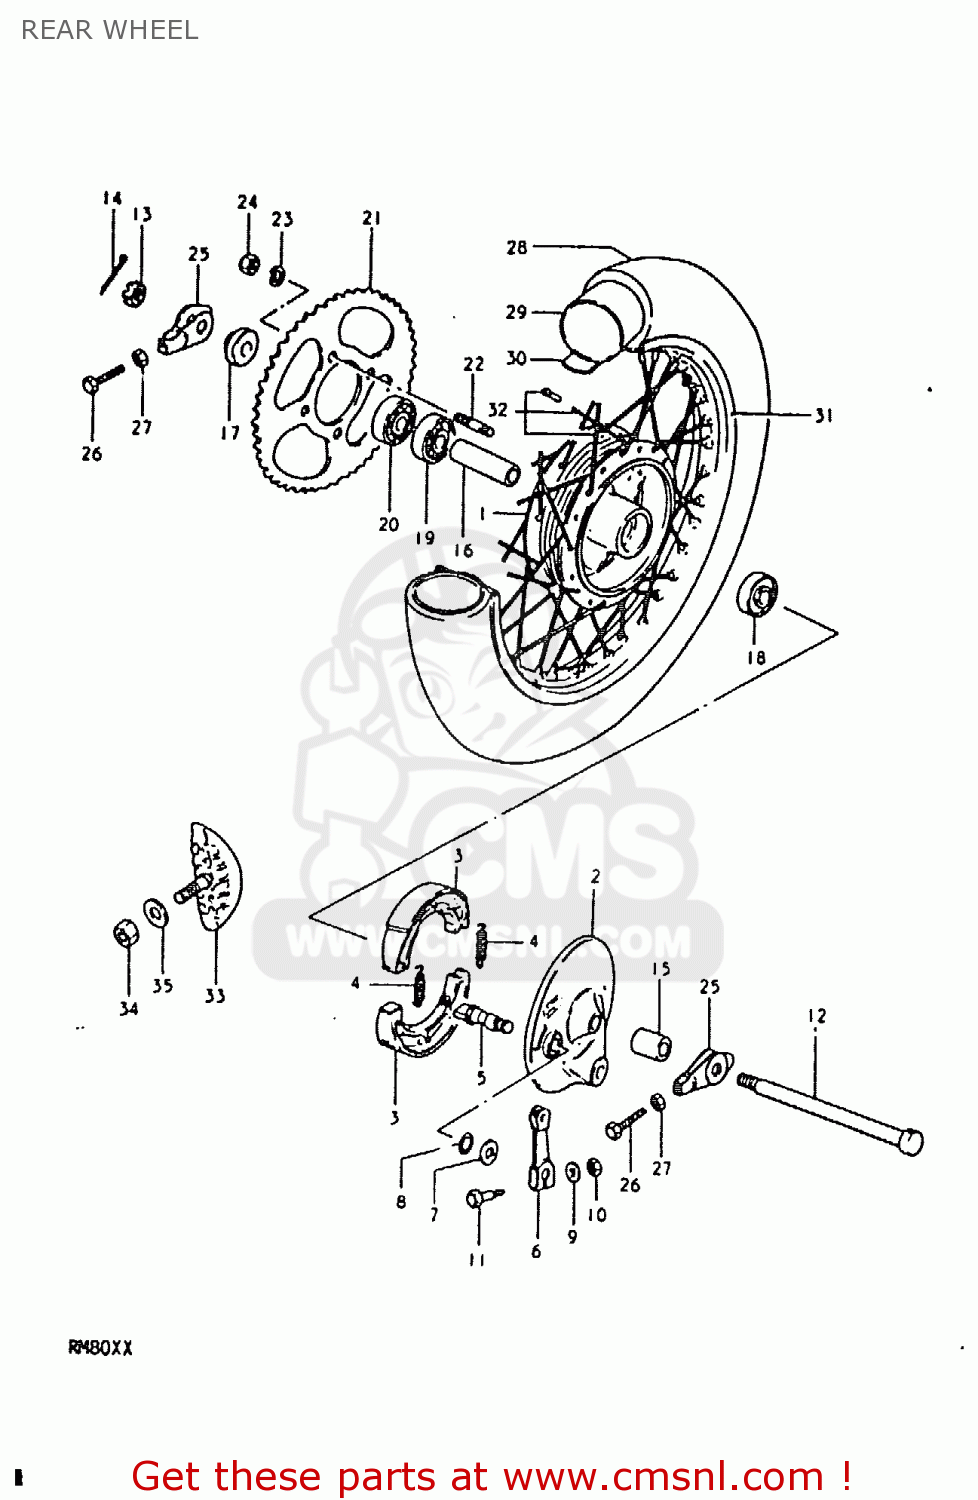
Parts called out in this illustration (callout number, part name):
1	DRUM SET,REAR HUB
2	PANEL,REAR BRAKE ANCHOR
3	SHOE,BRAKE (MCA)
4	SPRING(L:34)
5	CAM,FRONT BRAKE
6	LEVER,RR BRAKE CAM
7	WASHER (14.5X22X1.6)
8	O-RING (D:2.4 ID:13.8)
9	WASHER
10	NUT
11	BOLT(6X33)
12	AXLE,REAR
13	NUT 12MM
14	COTTER PIN
15	SPACER (12.1X22X27)
16	SPACER (12.6X19X79)
17	SPACER,RR AXLE,L
18	BEARING
19	BEARING
20	BEARING
21	SPROCKET,REAR
22	BOLT
23	LOCK WASHER
24	NUT
25	26
26	BOLT(6X38)
27	NUT
28	TIRE
29	TUBE ASSEMBLY,WHEEL,INNER
30	PROTECTOR,INNER TUBE
31	RIM,REAR WHEEL
32	SPOKE ASSY,RR WHEEL
33	STOPPER,BEAD
34	NUT
35	WASHER
